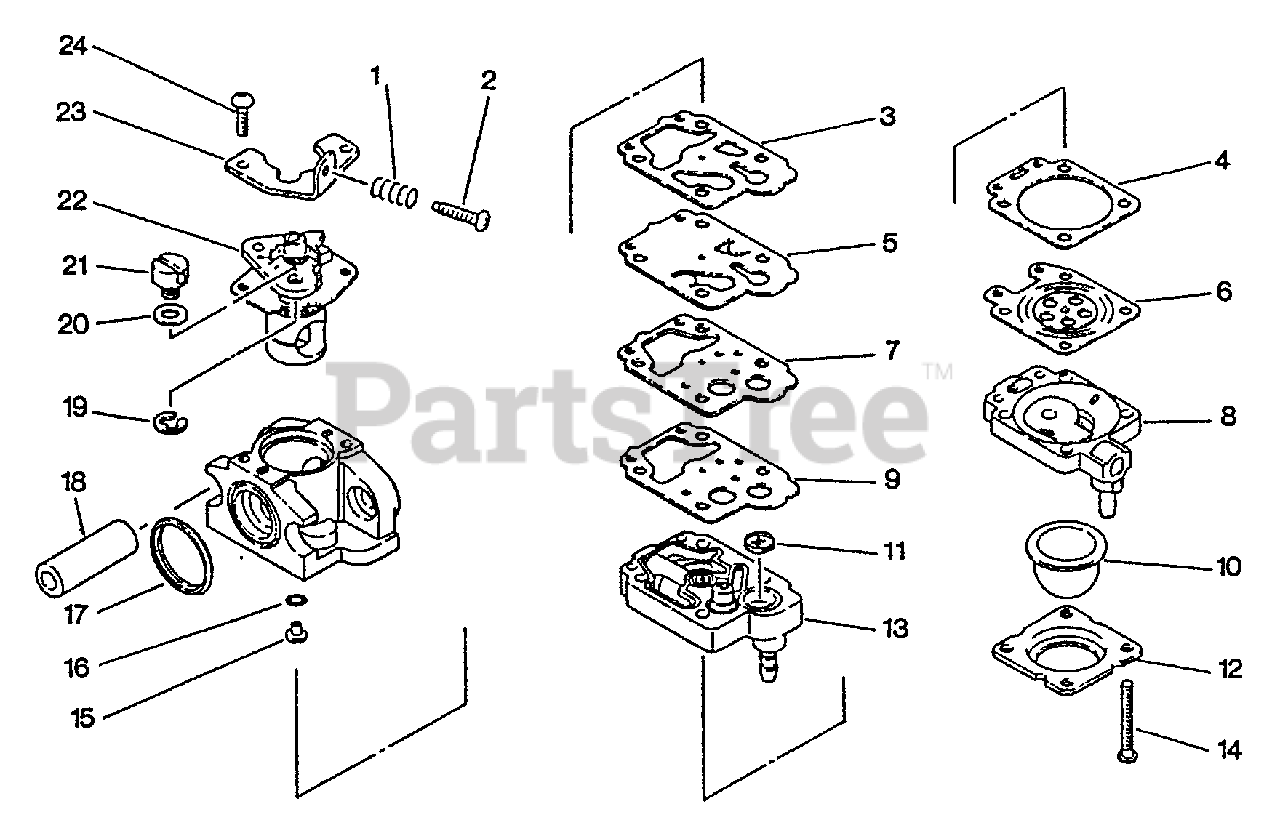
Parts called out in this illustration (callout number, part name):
1	SPRING, IDLE ADJUST
2	SCREW, IDLE ADJUST
3	GASKET, PUMP
4	GASKET, MTRING DIAPHRAGM
5	DIAPHRAGM, PUMP
6	DIAPHRAGM, METERING
7	PLATE, PUMP
8	BASE, PURGE
9	GASKET, PLATE
10	BULB, PURGE
11	BASE, PURGE
12	RETAINER, PURGE BULB
13	BASE, PURGE
15	BASE, PURGE
16	BASE, PURGE
17	SEAL
18	SLEEVE, MOUNTING
19	RING, RETAINING
22	VALVE, THROTTLE
23	BRACKET, THROTTLE CABLE
A	REPAIR KIT
B	DIAPHRAGM/GASKET KIT
